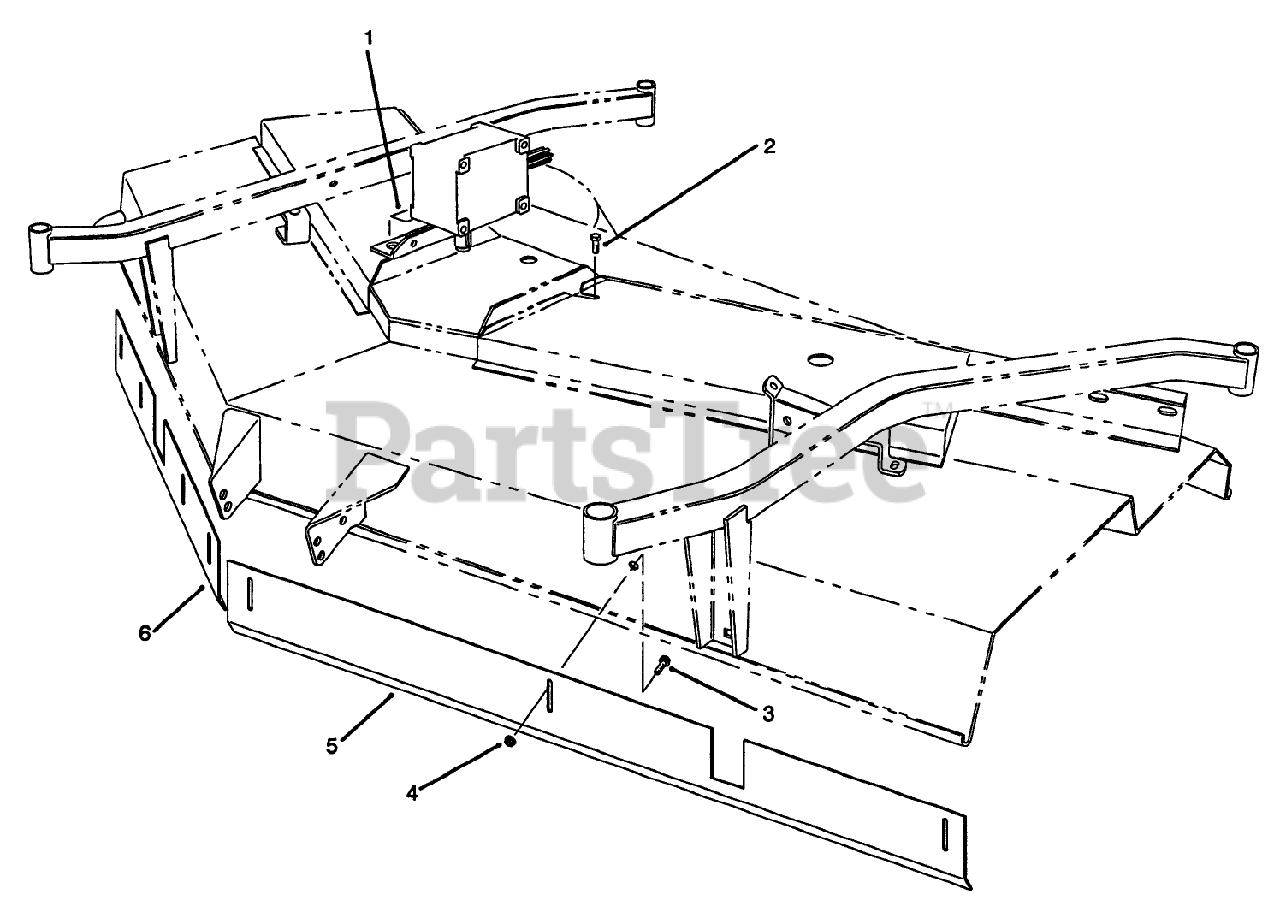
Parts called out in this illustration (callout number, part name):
1	DECAL-LUBE
2	SCREW-HH
3	SCREW-HHF
4	NUT-HF
5	Baffle-LH
6	Baffle-RH
